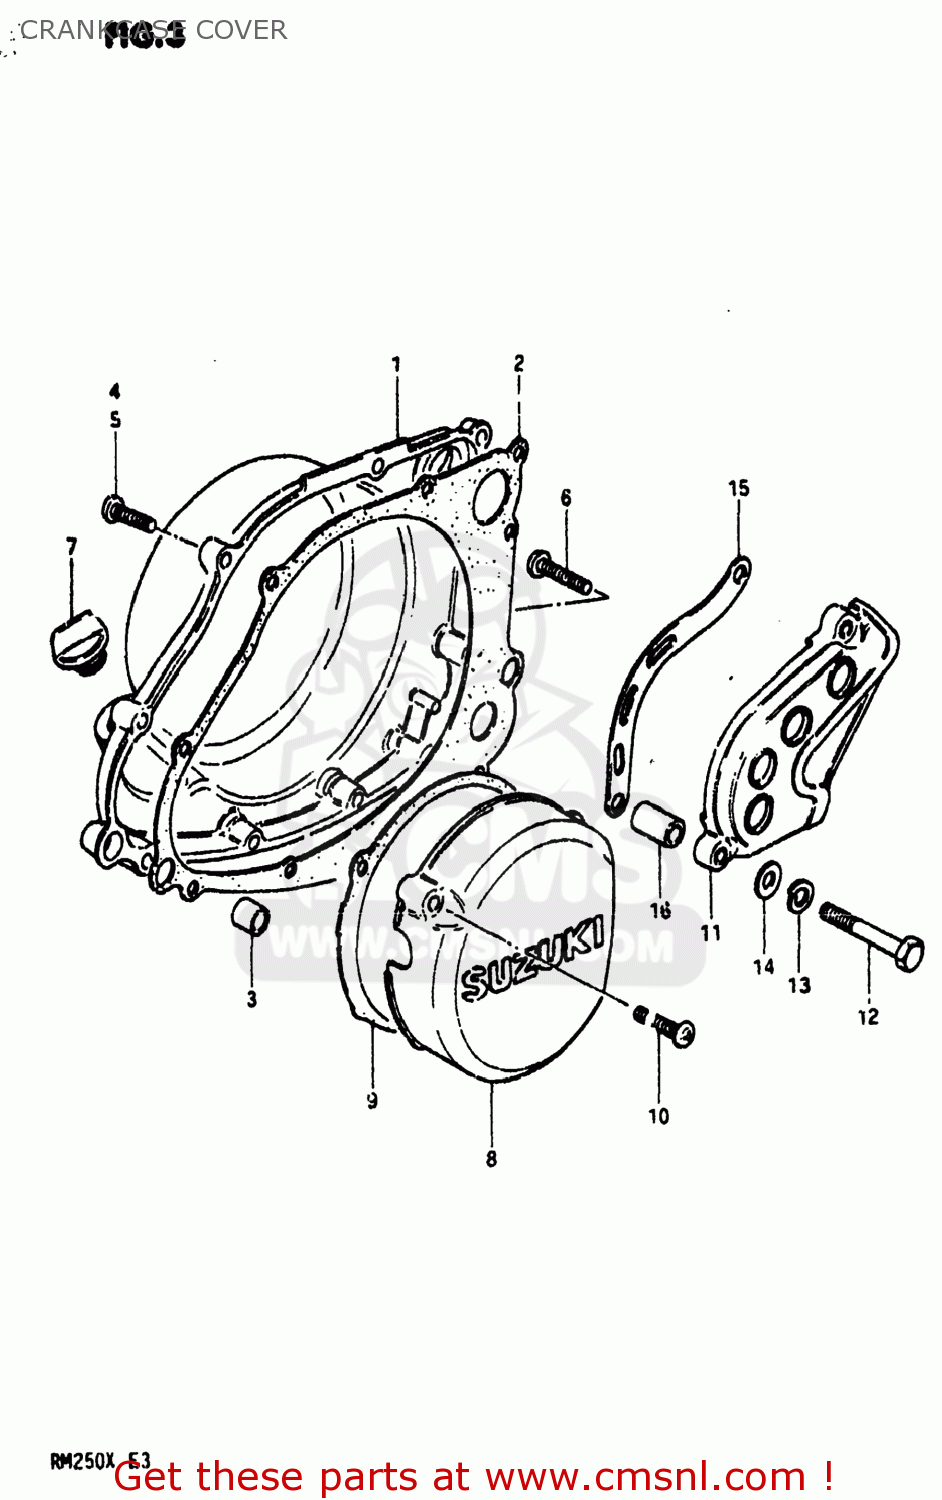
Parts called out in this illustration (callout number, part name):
1	COVER,CLUTCH
2	GASKET,CLUTCH COVER (MCA)
3	PIN
4	SCREW
5	SCREW 6X30
6	SCREW (6X45)
7	PLUG,OIL FILTER
8	COVER,MAGNETO
9	GASKET,MAGNETO COVER (MCA)
10	SCREW
11	COVER,ENGINE SPROCKET
12	BOLT 8X55
13	LOCK WASHER
14	WASHER
15	PLATE,FR CHAIN GUIDE
16	SPACER(8.6X16X24)
